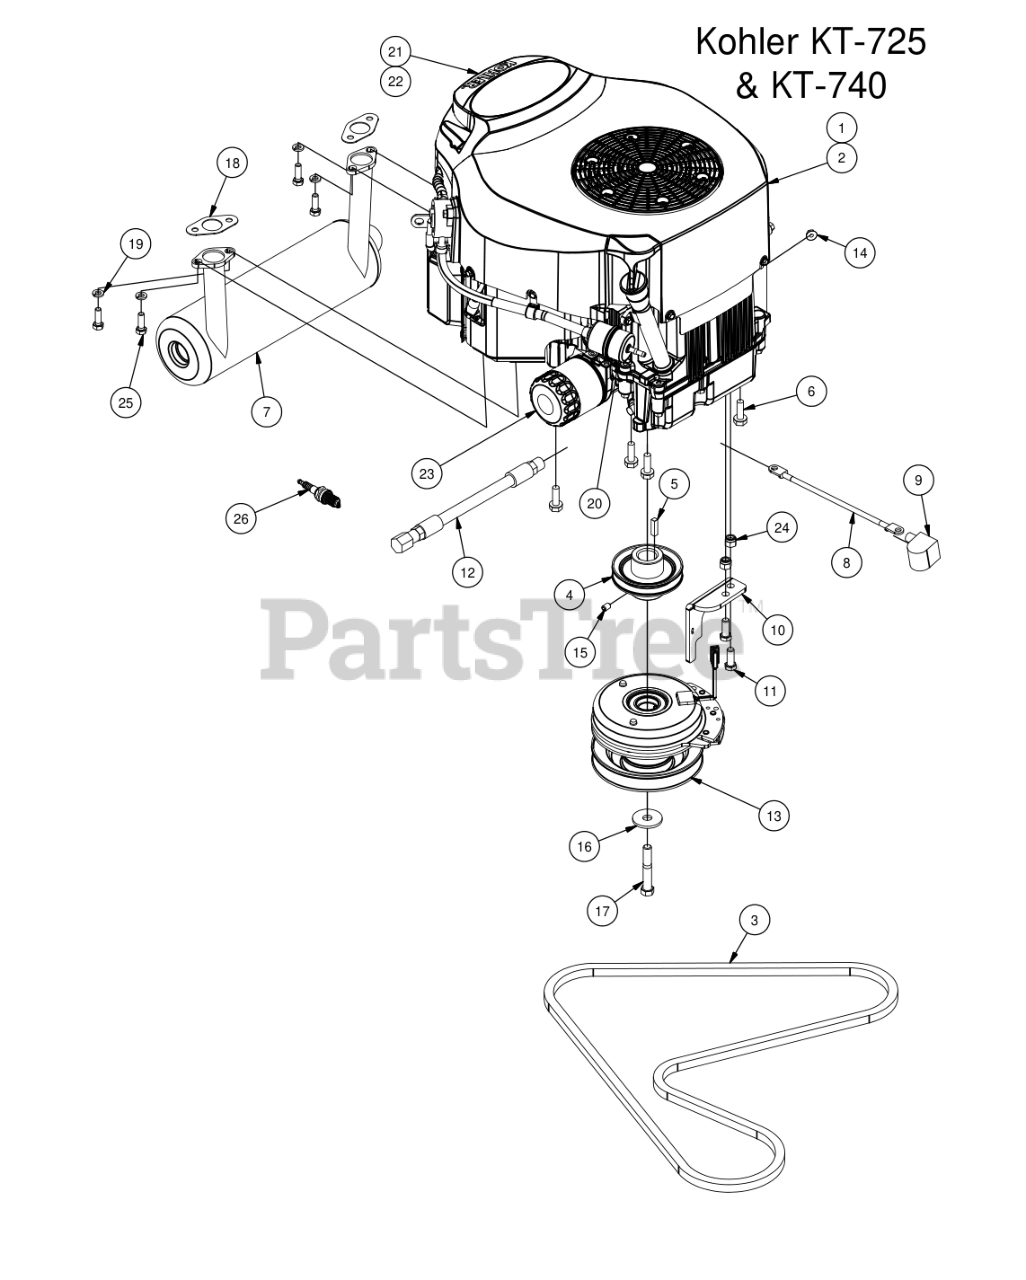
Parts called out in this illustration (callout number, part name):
1	Kohler KT-740
2	Kohler KT-725
4	3-3/4" Motor Pulley
5	1/4" x 1" Key
6	3/8 x 1 1/8 bolt
7	2014 MZ Muffler-725cc Kohler
8	Ground Cable
9	Black Boot For Ground Cable
10	Warner Clutch A-R Bracket
11	3/8" x 1" Hex Bolt
12	Oil drain Hose
13	Clutch 2015 Magnum/MZ
14	1/4-20 Hex Flange Nuts Zinc w/Serrations
15	3/8" Set Screw
16	1/2 Belleville Washer
17	7/16" x 4" Fine Thread Bolt
18	Exhaust Gasket
19	5/16" Lock Washer
20	Universal Fuel Filter
21	KT-725 & KT-740 Precleaner
22	KT-725 & KT-740 Air Elemet
23	KT-725 & KT-740 Oil Filter
24	3/8 Nylock Nut
25	5/16" x 1" Bolt
26	Spark Plug
